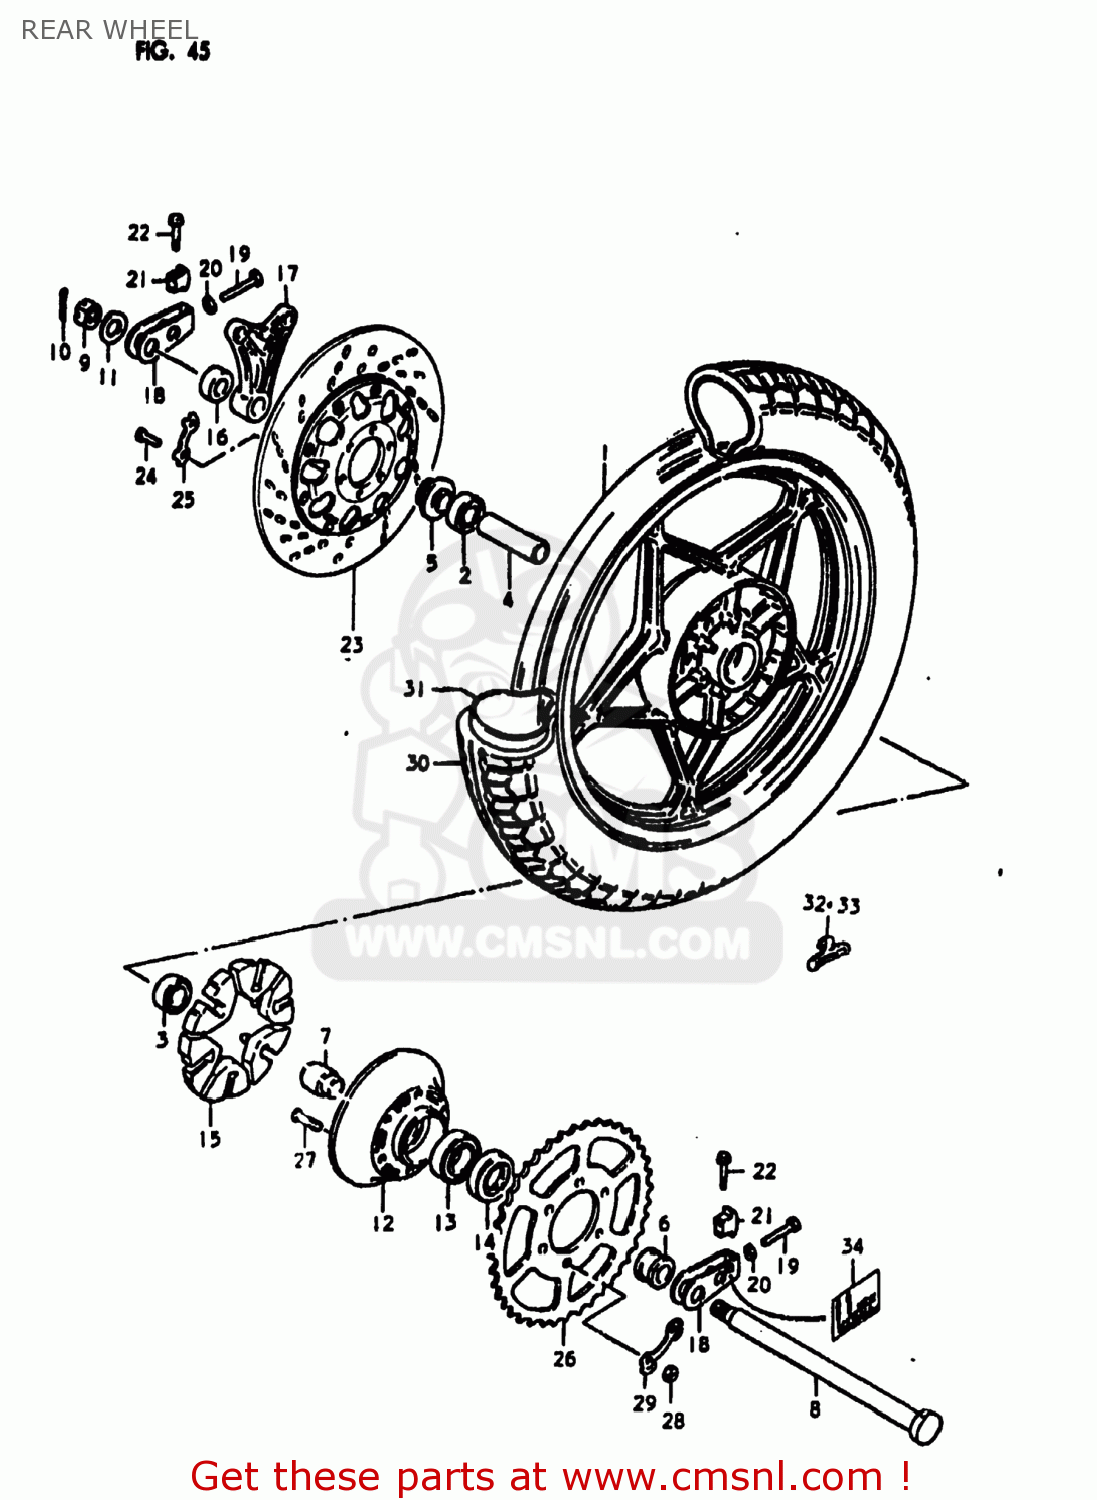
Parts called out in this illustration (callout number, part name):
1	WHEEL,REAR
2	BEARING WHEEL REAR(20X47X14)
3	BEARING, LH
4	SPACER(20.5X28X88)
5	SPACER,REAR AXLE
6	SPACER
7	SPACER,REAR HUB BEARING
8	AXLE,REAR
9	NUT 18MM
10	PIN,COTTER
11	WASHER(19X34X4)
12	DRUM,REAR SPROCKET MOUNT
13	BEARING
14	SEAL,OIL(33X62X7)
15	ABSORBER,REAR HUB SHOCK
16	SPACER(20X38X12)
17	BRACKET,RR,CALIPER
18	ADJUSTER,CHAIN
19	BOLT 8X50
20	NUT
21	SUPPORTER,CHAIN ADJUST
22	BOLT 8X40
23	DISC,RR BRAKE
24	BOLT(8X30)
25	WASHER
26	SPROCKET,RR(NT:40)
27	BOLT
28	NUT
29	WASHER
30	TIRE
31	TUBE ASSEMBLY,WHEEL,INNER
32	BALANCER,WHEEL
33	BALANCER,WHEEL
34	LABEL,CHAIN WEAR INDICATOR
